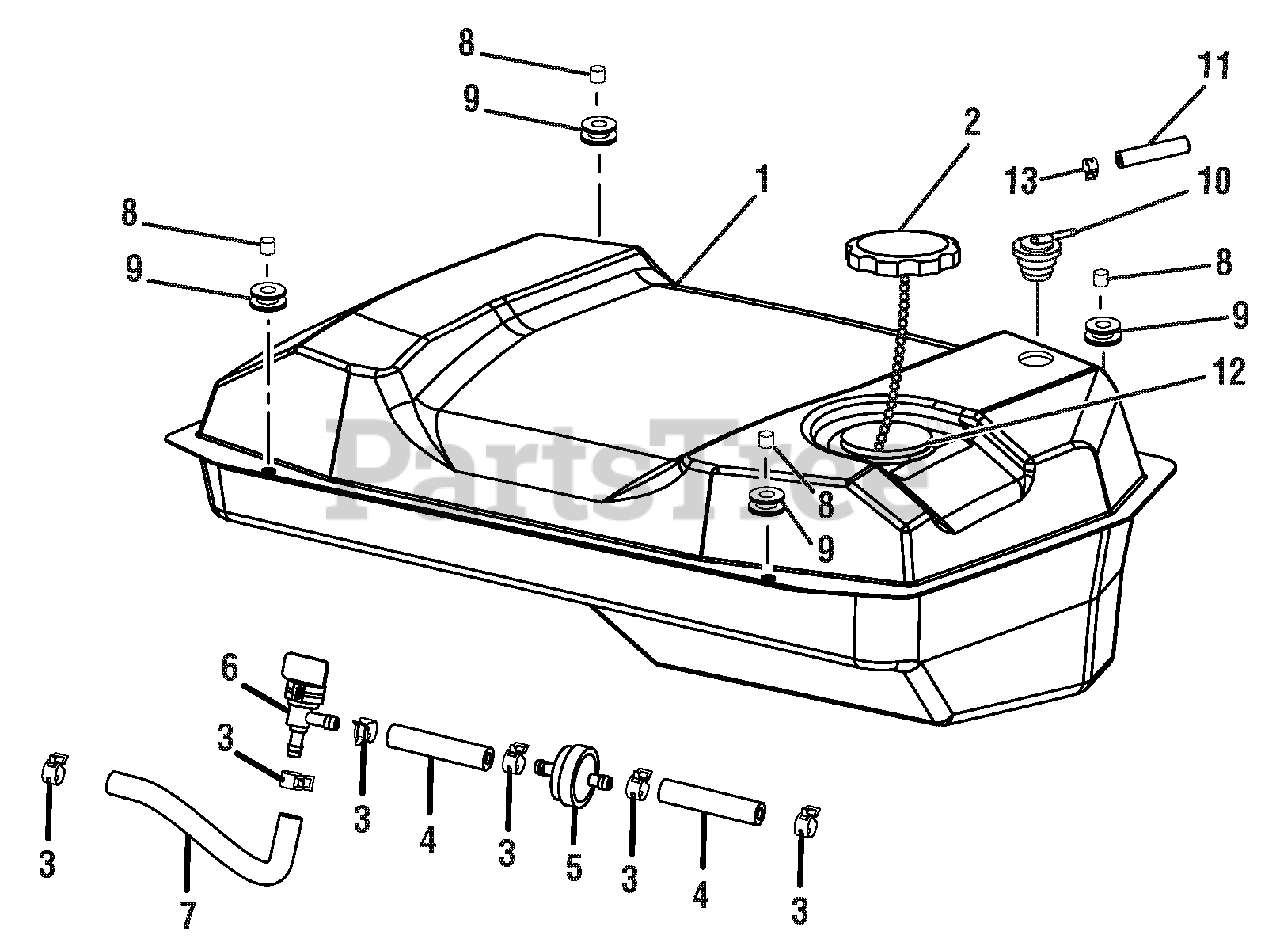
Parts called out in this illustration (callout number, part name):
1	Fuel Tank
2	Fuel Tank Cap
3	Fuel Line Clamp (1/2 in.)
4	Fuel Line (105 mm)
5	Fuel Line Filter
6	Fuel Shut Off Valve
7	Fuel Line (208 mm)
8	Spacer (Fuel Tank Isolator)
9	Bushing (Fuel Tank Isolator)
10	Vapor Vent
11	Purge Hose
12	Ring Clip
13	Fuel Line Clamp (7/16 in.)
